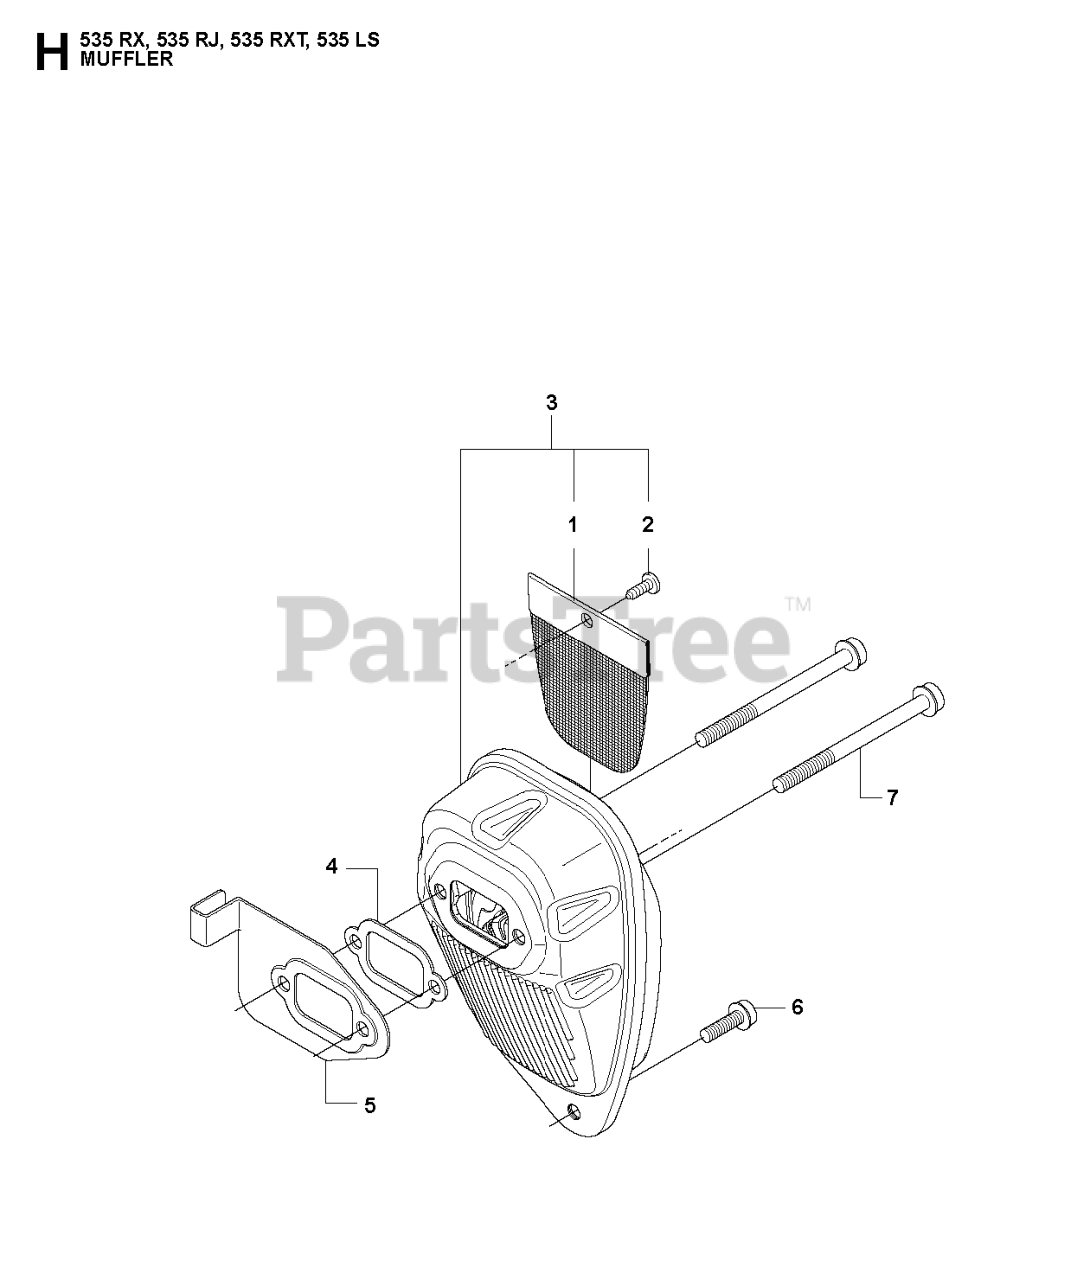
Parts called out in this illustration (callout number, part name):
1	SPARK ARRESTER SCREEN
3	MUFFLER
4	GASKET MUFFLER
